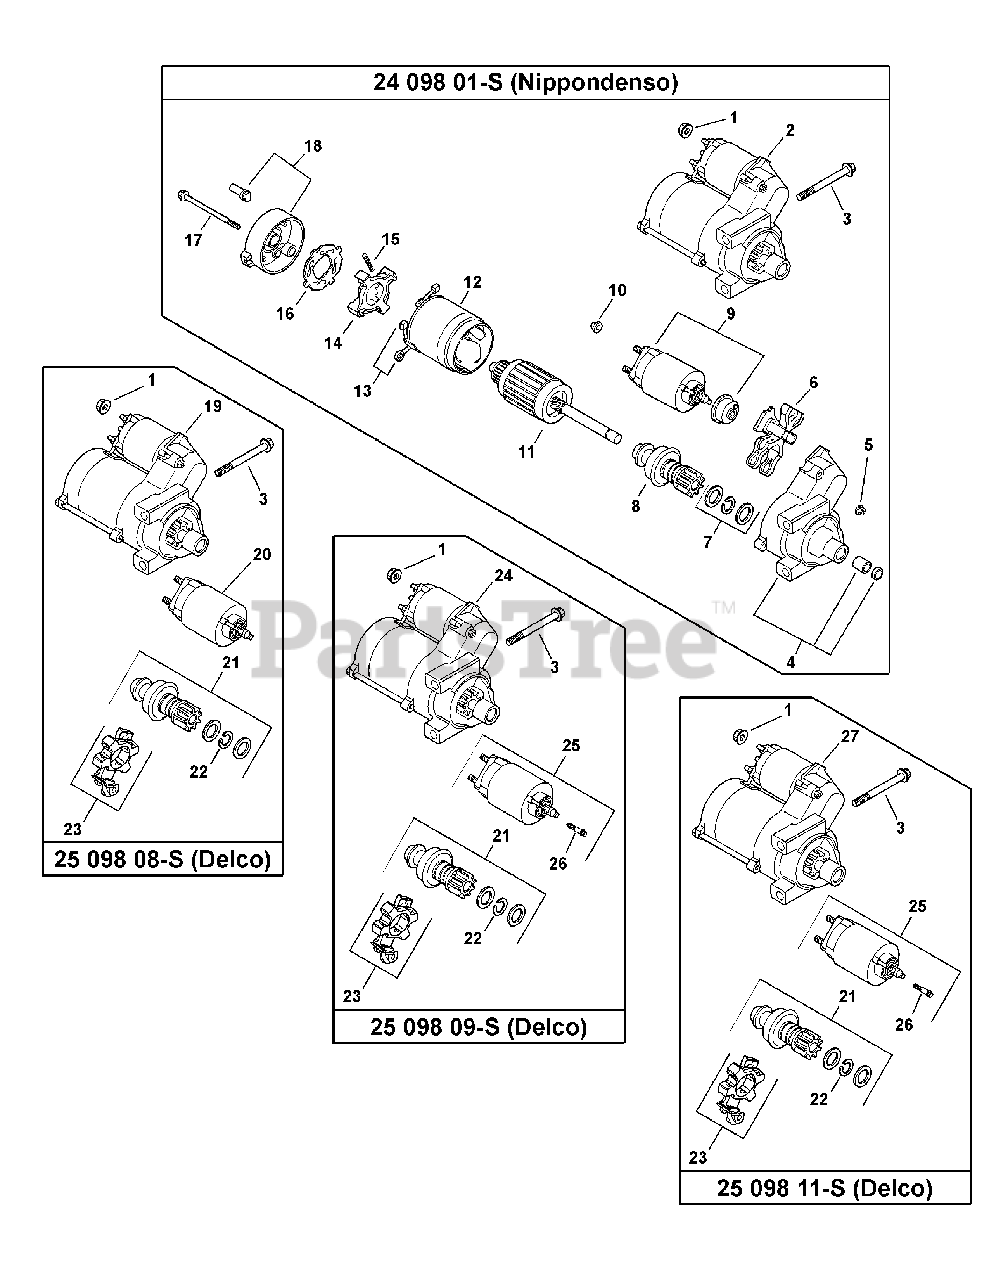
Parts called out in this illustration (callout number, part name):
1	NUT, FLG M8X1.25
2	STARTER
4	DRIVE, END CAP
6	LEVER, DRIVE
7	KIT, STARTER REPAIR
8	DRIVE PINION
12	FRAME W/BRUSHES
13	BRUSH HOLDER
14	BRUSH & SPRING KIT
15	SPRING, BRUSH
18	COMMUTATOR, END CAP
19	STARTER, SOLENOID SHIFT
21	KIT, STARTER PINION
22	RING, RETAINING
23	KIT, BRUSH HOLDER
24	STARTER
25	KIT, SOLENOID
26	SCREW, EXTERNAL TORX HEAD
27	STARTER, SOLENOID SHIFT
